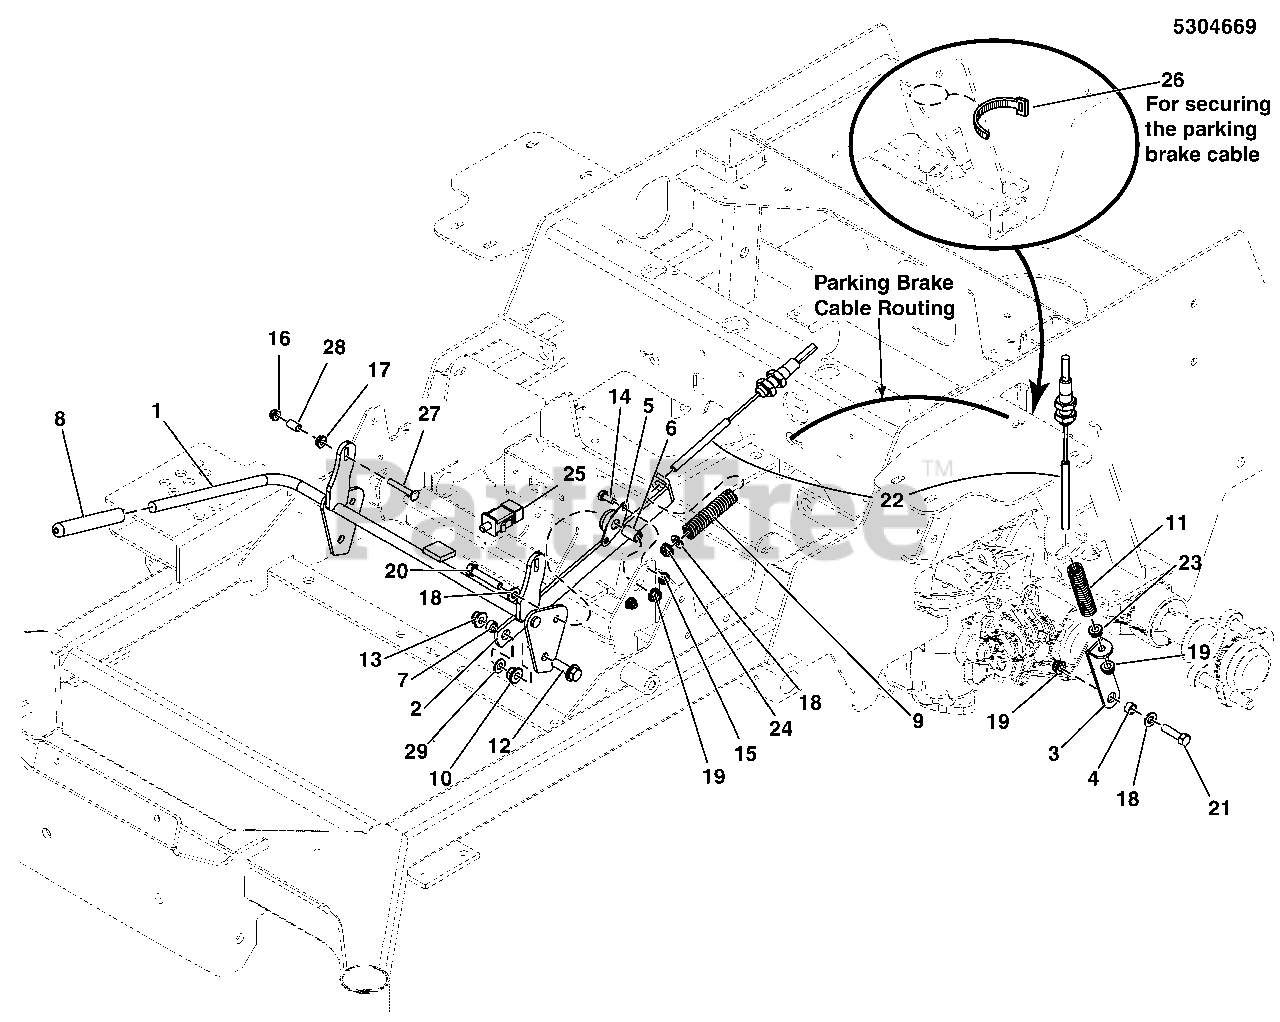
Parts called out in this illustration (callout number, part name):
1	WELD, BRAKE SHAFT, 600/700/125/560 - BLK
2	LINK, BRAKE LOCK, IS700 - BLK
3	LINK, LOWER BRAKE, IS700 - BLK
4	SPACER, .33 X .50 X .25, PM, CZ
5	BEARING, 1/2 FLANGED, PLASTIC BALL
6	SPACER, .32 X .50 X .83, CZ
7	SPACER, .38 X .50 X .27, CZ
8	GRIP, FOAM, .475 X 4.35 X .095
9	SPRING-COMP, .496ID X 3.00LG X .112WR
10	NUT, 3/8-16 HEX SERRATED FLANGE
11	SPRING-COMP, .600ID X 5.50LG X .080WR
12	BOLT, 3/8-16 X 1-1/2, FLANGE, GD 5, CZ
13	NUT, 3/8-16 HEX NYLOCK FLANGE
14	HHCS, 1/4-20 X 0.625, GR5, ZINC/CLEAR
15	NUT, 1/4-20 HEX NYLOCK FLANGE
16	NUT, 1/4-20 HEX NYLON LOCK
17	NUT, 1/4-20 HEX SERR. FLANGE
18	WASHER, 5/16" SAE
19	NUT, 5/16-18 HEX NYLOCK FLANGE
20	BOLT, 5/16-18 X 1-3/4 GD5 CZ
21	BOLT, 5/16-18 X 1-1/8 GD5 CZ
22	CABLE,PARKING BRAKE, 31" (787.9MM)
23	NUT, 5/16-18 HEX
24	NUT, 5/16-24 HEX NYLON LOCK
25	SEE ELECTRICAL GROUP
26	TIE, SELF-LOCKING, 12"
27	BOLT, 1/4-20 X 1.500, GR5, SQ, ZINC/CLEA
28	SPACER, .25 X .38 X .63
29	WASHER, 5/16 USS
